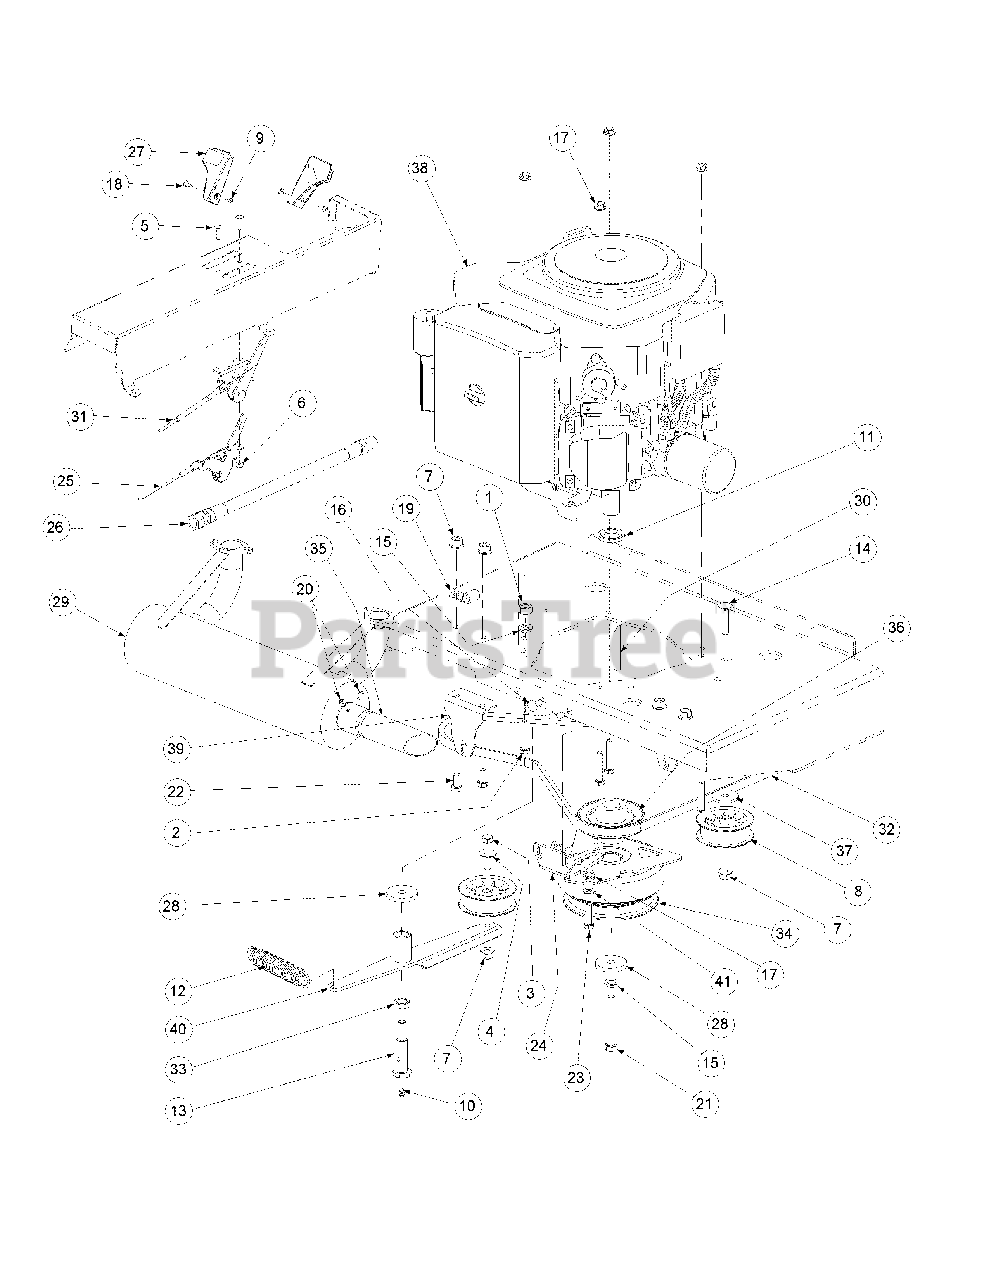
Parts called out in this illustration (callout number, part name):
1	Hex Nut, 7/16-14
2	HHCS, 5/16-18, 1-3/4
3	Capscrew, 3/8-16 x 1-3/4
5	Round Hd. Machine Screw, 10-32 x 3/4
6	Lock Nut, Nylon Insert, 10-32
7	Flange Lock, Hex Nut, 3/8-16
8	Idler Pulley w/ Adaptor
9	Nut Washer, W/Star, 8-32
10	Grease Fitting, 1/4-28 x 3/16
11	Engine Spacer
12	Extension Spring, 1.0 OD x 5.00
13	Shoulder Screw, 7/16-14
14	Hex Carriage Screw, 3/8-16, 1.75
15	Lock Washer, 7/16
16	Carriage Bolt:5/16-18 x 3/4
17	Hexflange Lock Nut, 5/16-18
18	Machine Screw, 8-32, .375
19	Clip, Heat Shield Cable
20	Tube Clamp, 1.375
21	Capscrew, 7/16-20 x 3.00
22	Hex Cap Screw, 3/8-16, .750
23	Hex Cap Screw:5/16-18 x 1-1/4
24	Retainer Clutch Assembly, Ogura
25	Throttle, Control Cable, 45.0
26	Oil Drain Hose
27	Control Throttle Knob
28	Flat Washer, 7/16 IDx 1.750 OD x .250T
29	23HP Kohler Exhaust
30	Key, 1/4 x 1/4 x 2.75
31	Choke, Control Cable, 38.0
32	V-Belt, 56.00
33	Spacer, .635 ID x .28
34	Electric Clutch
35	Muffler Accessory Exhaust Tube
36	Transmission Drive Pulley
37	Washer, 5/16-18
38	23HP Kohler Engine
39	Neutral Lock Mounting Bracket
40	Engine Idler Arm Assembly Includes:
41	Flat Washer, 5/16
